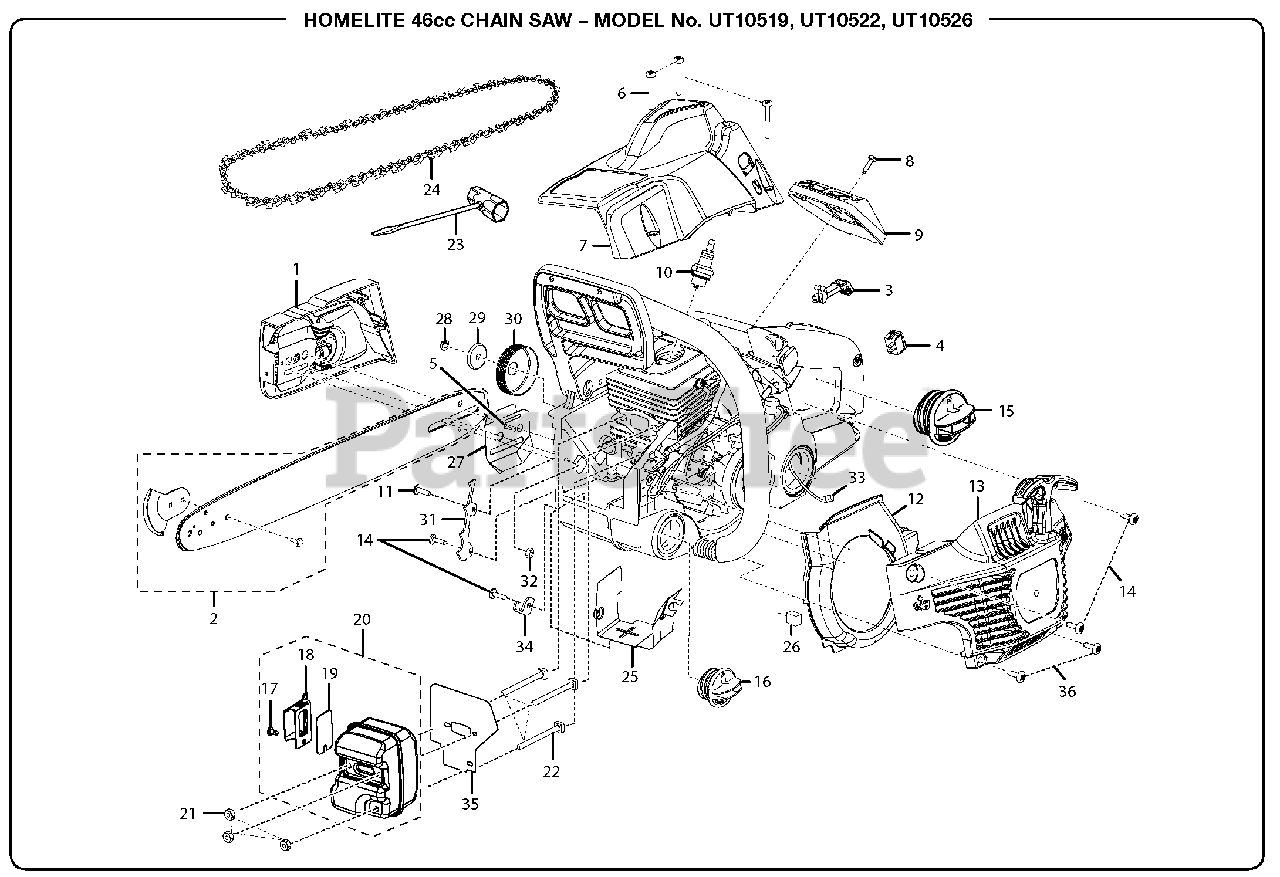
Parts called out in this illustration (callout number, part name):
1	Chain Cover Assembly
2	Guide Bar (20 in. with SAFE-T-TIP)
3	Choke Lever
4	Ignition Switch
5	Screw (6-19 x 1/2 in. T.F.)
6	Screw (10-16 x 1-1/2 in. Special)
7	Top Cover
8	Screw (8-16 x 16 mm Torx T.F.)
9	Air Filter Cover
10	Spark Plug (Champion RCJ6Y)
11	Screw (10-24 x 5/8 in. Torx Pan Hd.)
12	Fan Housing Baffle
13	Starter Cover Assembly
14	Screw (10-14 x 5/8 in. Torx Pan Hd.)
15	Fuel Cap Assembly
16	Oil Cap Assembly
17	Screw (8-32 x 5/16 in.)
18	Muffler Deflector
19	Spark Screen
20	Muffler Assembly (Includes Key Nos. 17-19)
21	Lock Nut (10-32)
22	Muffler Bolt (Square Hd.)
23	Combination Wrench
24	Chain (.325 x 78 link, 20 in.)
25	Heat Shield
26	Pre-Filter
27	Inner Guide Plate
28	E-Ring
29	Cupped Washer
30	Sprocket Drum and Bearing Assembly (.325 chain)
31	Spike Bar
32	Lock Nut (10-24)
33	Fuel Filter
34	Chain Catcher
35	Muffler Gasket
36	Screw (10-14 x 3/4 in.)
